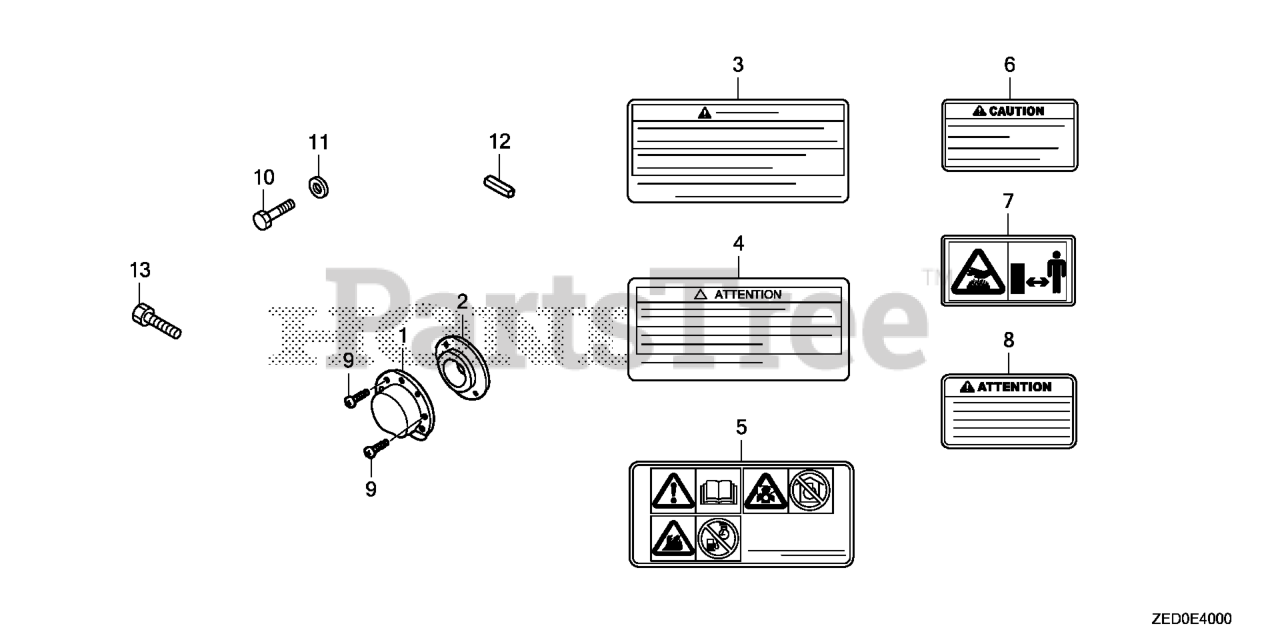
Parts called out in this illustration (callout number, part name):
1	DEFLECTOR
2	GUIDE, MUFFLER
3	MARK, OPERATOR CAUTION (ENGLISH)
4	MARK, OPERATOR CAUTION (FRENCH)
6	MARK, EX. CAUTION (ENGLISH)
8	MARK, EX. CAUTION (FRENCH)
9	SCREW, TAPPING (4X8)
12	KEY (5X5X33)
